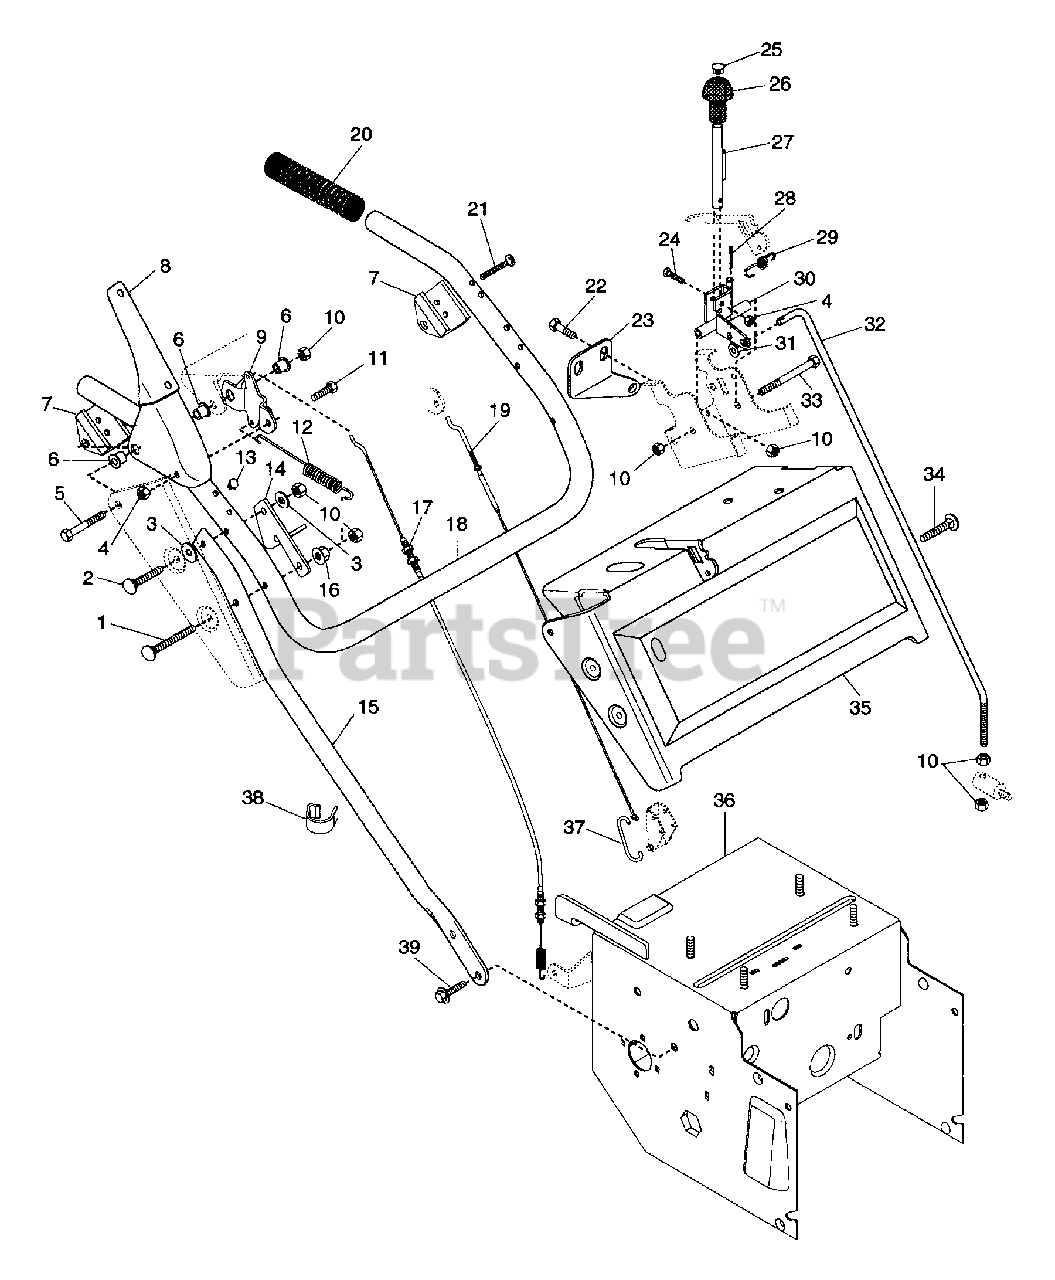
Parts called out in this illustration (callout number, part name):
1	BLT-RDHDSQNK .31-18X2.75 SHPL
2	BLT-RDHDSQNK .31-18X1.50 PL
3	WSHR-FL-STL .438X1.0X.083 PL
4	NUT-LK-CTR .250-20 PL
5	BLT-HEX .31-18X2.50 PL GR2
6	BSHG-FLG .325X.465X.333X.685
7	HANDLE PIVOT
8	CLUTCH LEVER - COATED
10	NUT-LK .312-18 GR A PL
11	BLT-HEX .25-20X.38 PL GR2
12	SG-TENS .051X.50X5.12 WLD 10.4
14	UPPER CABLE ANCHOR R H
15	L H LOWER HANDLEBAR
16	NUT-FLG. .312-18 PL
17	CLUTCH CABLE - ATTACHMENT
18	UPPER HANDLEBAR
19	CABLE, ADJUSTABLE
20	HANDLE GRIP
21	SCR-TAP 12-14X1.50 CROVH PL BT
22	BLT-HEX .31-18X.50 PL GR2
23	CHUTE CRANK BRACKET
24	BLT-HEX .31-18X1.50 PL GR5
25	HOLE PLUG
27	ROD
28	PIN-COTR .09X.75 PL
29	SG-TENS .055X.33X1.31 WLD 7
31	WSHR-FL-STL .323X.625X.062 PL
32	SHIFT ROD
33	BLT-HEX .31-18X3.50 PL GR2
34	BLT-RDHDSQNK .31-18X1.75 SHTPL
35	PANEL
36	FRAME
37	FRAME
39	BLT-SERHFWH .31-18X.62 PL
